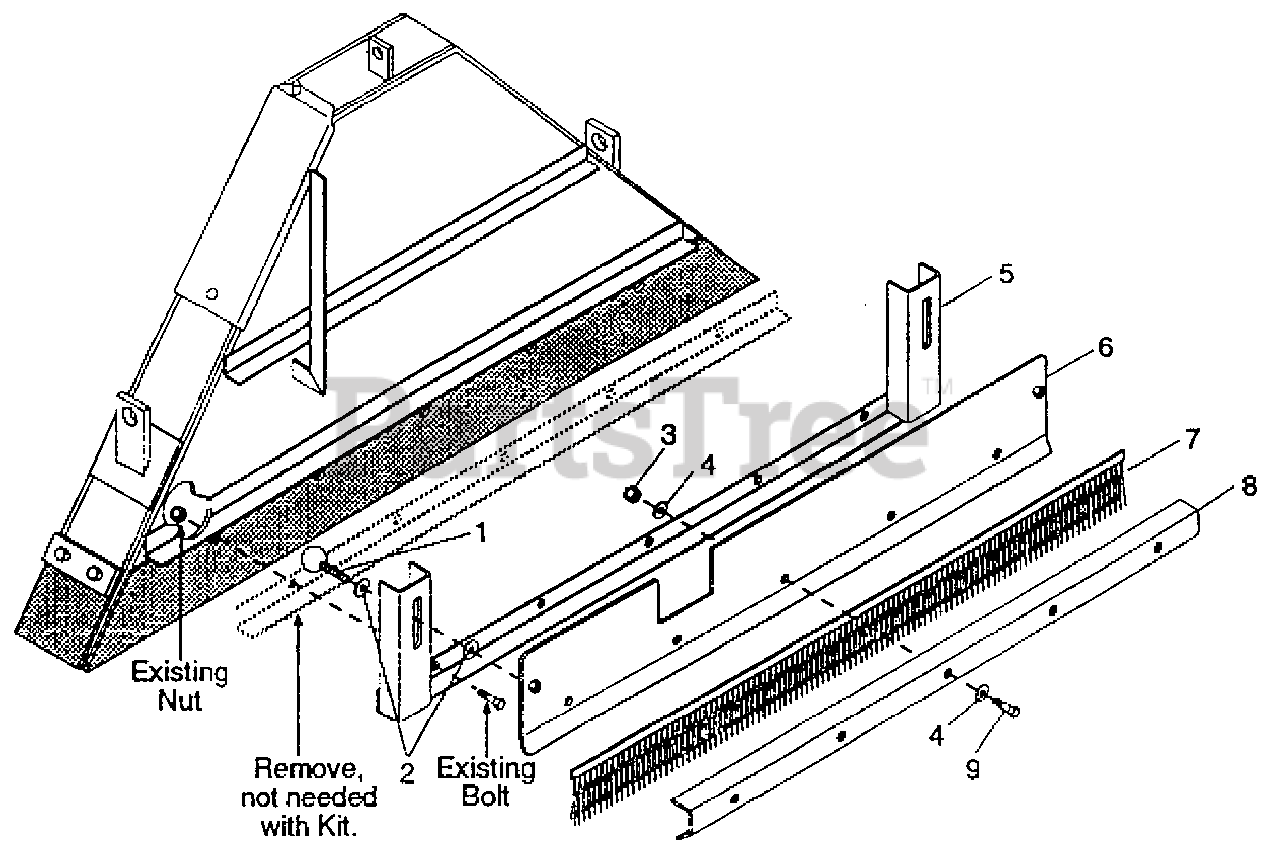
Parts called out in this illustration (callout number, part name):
1	Adjustment Screw
2	Wshr-Fl-St .438 x 1.0 x .083 Pl
3	Nut-Lk-Top .375-16 Gr C Pl
4	Wshr-Fl-St .38 x .875 x .083
5	Mount Weldment
6	Back Plate
8	Clamp Bar
9	Blt-Hex .38-16 x 1.50 Pl Gr 5
